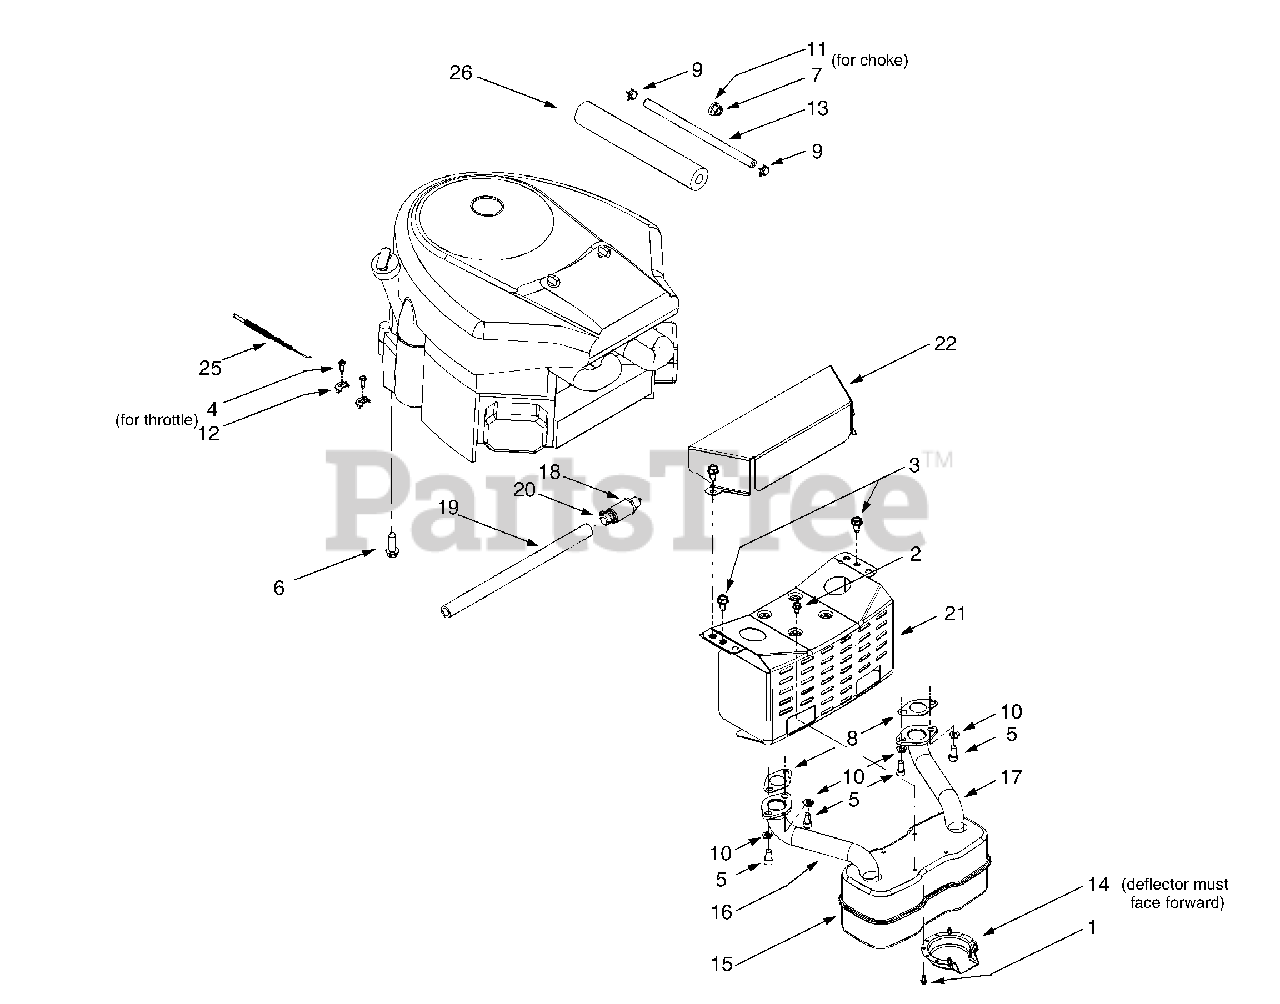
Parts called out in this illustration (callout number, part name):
1	Self-tapping Screw, #8-32 x .375
2	Self-tapping Screw, 1/4-20 x .5
3	Self-tapping Screw, 5/16-18 x .625
4	Screw, #10-32 x .625
5	Socket Cap Screw, 5/16-18 x .625
6	Self-tapping Screw, 3/8-16 x 1.25
7	Hex Nut, 3/8-16
8	Exhaust Gasket
10	Lock Washer, 5/16
11	Flat Washer, .406 x ..875 x .059
13	Fuel Line Hose
14	Muffler Deflector
15	Muffler, Twin Inlet
16	RH Exhaust Pipe
17	LH Exhaust Pipe
18	Oil Drain Valve
19	Oil Drain Hose
20	Oil Drain Cap
22	Engine Heat Shield
25	Throttle Cable
26	Foam
